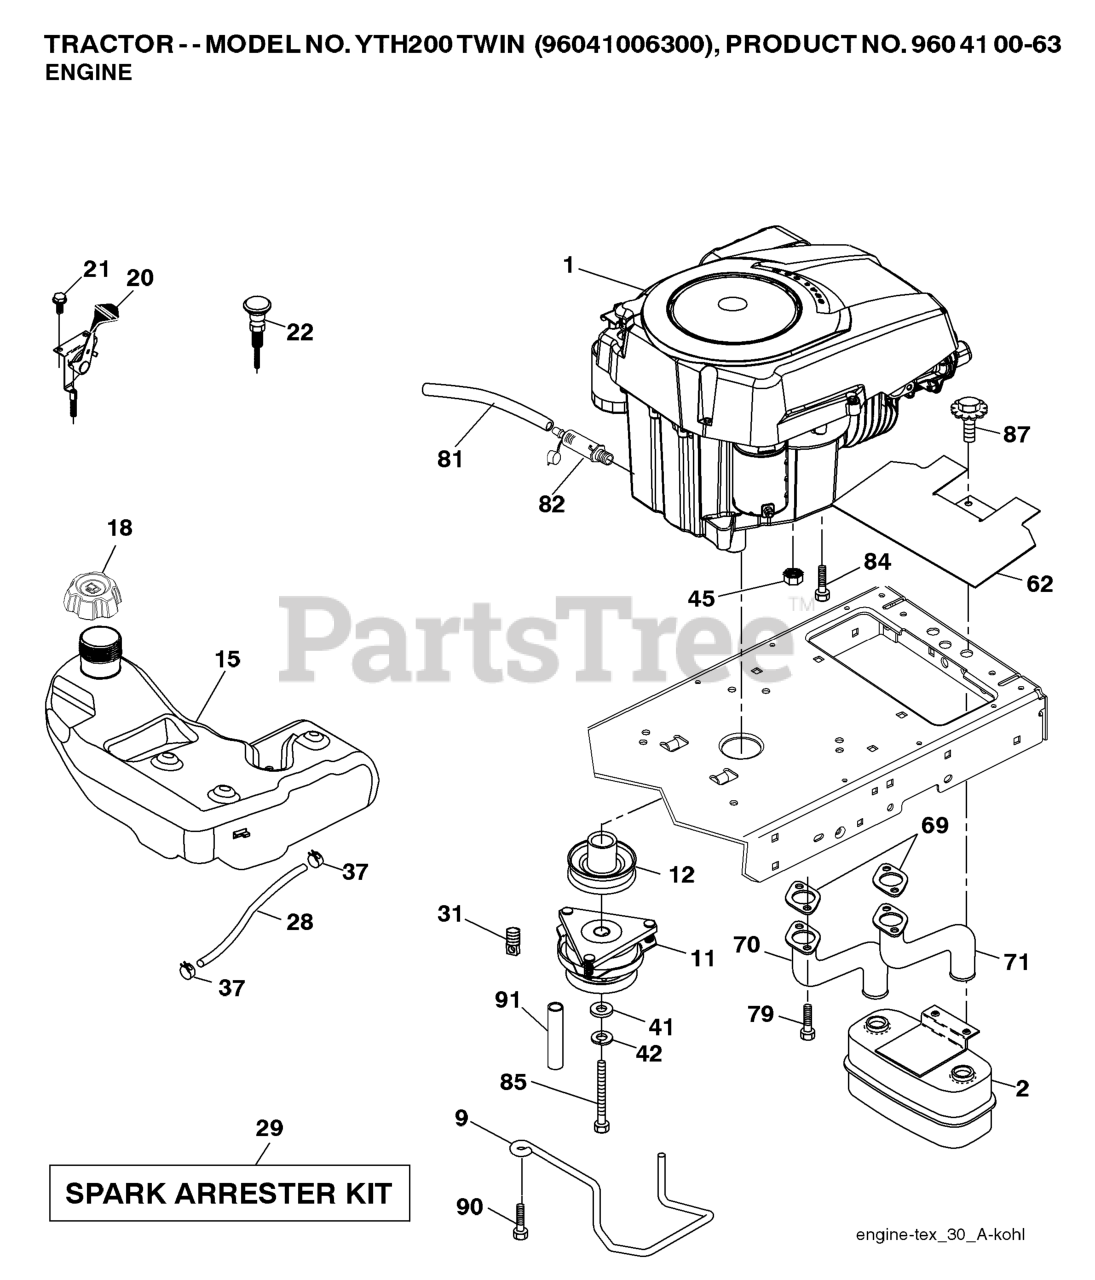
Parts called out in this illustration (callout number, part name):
2	MUFFLER.TWIN.CYL.LOW.TONE
9	KEEPER.BELT.ENGINE.4.2
11	CLUTCH.ELECTRIC.LT.48"*
12	PULLEY.ENGINE.TUFFTORQ
15	TANK.FUEL.4GAL
18	CAP.FUEL.TANK.3"GREY
20	THROTTLE CONTROL
21	SCREW
22	CONTROL.CHOKE.ERGO.PUSH-IN.BLA
28	REPL BY 532 00 85-43
29	KIT.SPARK ARRESTOR 794945 B&S
37	HOSE CLAMP
42	LOCKWASHER
45	NUT
62	RP SHIELD HEAT MUFFLER
69	GASKET.EXHAUST.KOHL.CV18-CV26
70	RP.PIPE-EXHAUST LH
71	RP.PIPE-EXHAUST RH
79	SCREW.SOCKET HD.5/16-1
81	TUBE, DRAIN OIL ASM.
82	PLUG DRAIN OIL EASY
84	SCREW 3/8-16X1
85	BOLT HEX 7/16-20X4-1/4"
87	BOLT.5/16-18UNCX3/4 W/SEMS.BLK
90	SCREW 3/8-16X1
91	BUSHING.1.375OD
